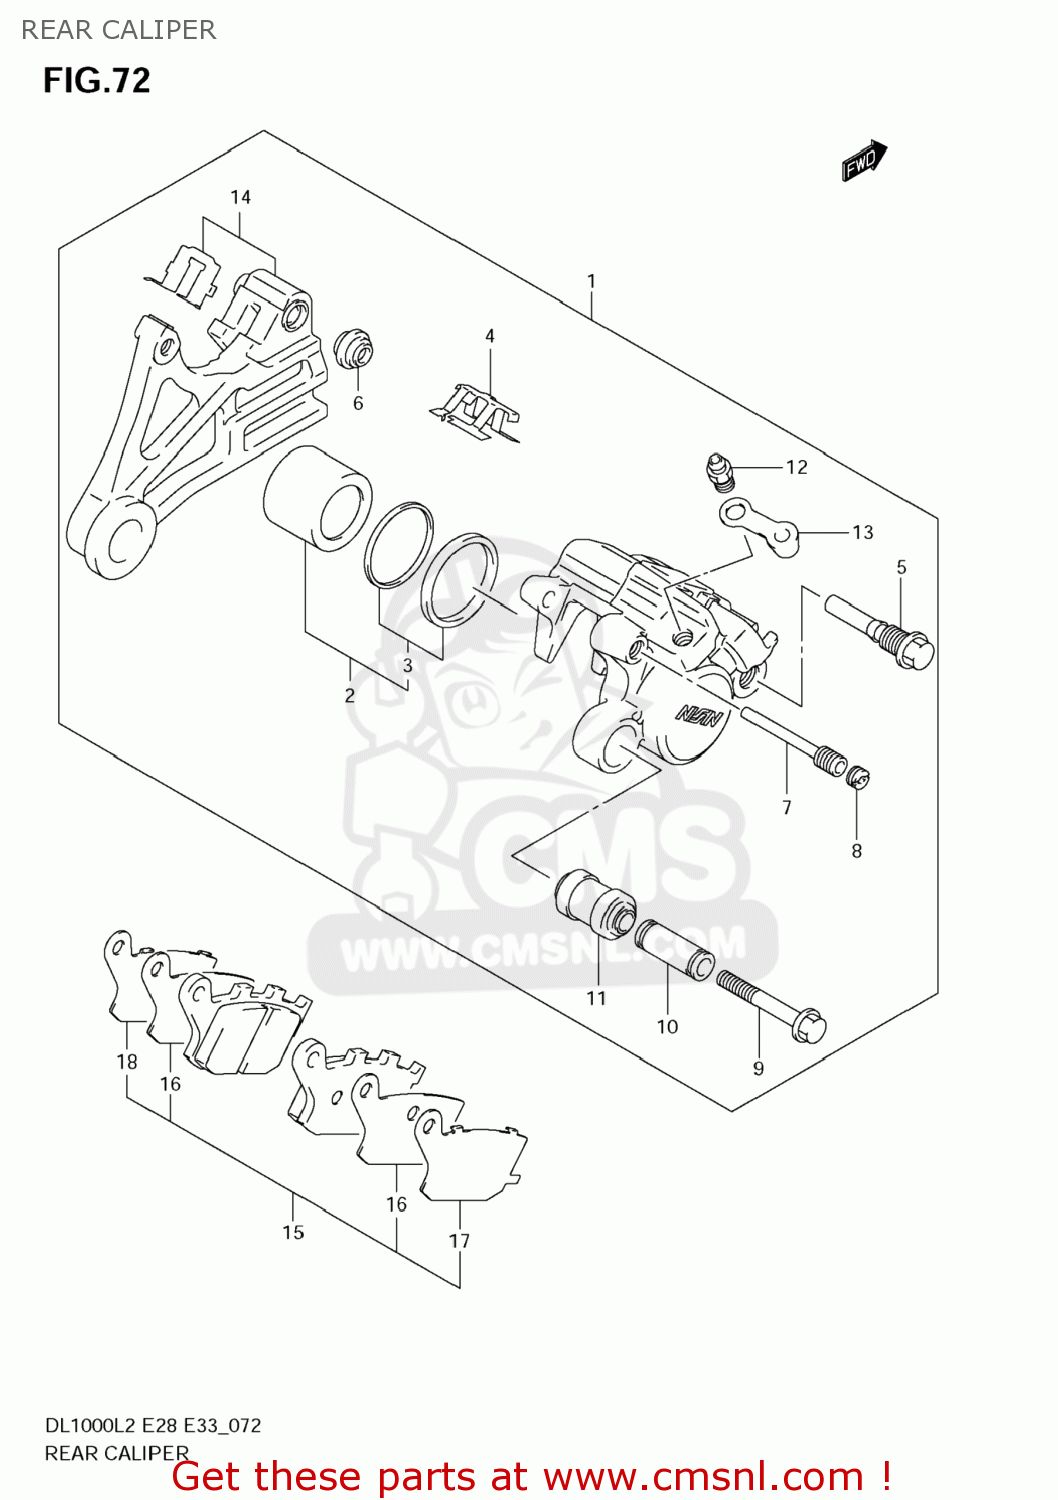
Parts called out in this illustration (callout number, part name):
1	CALIPER ASSY,RR
2	PISTON SET
3	SEAL SET,PISTON
4	SPRING,PAD
5	BOLT
6	BOOT
7	PIN,PAD
8	PLUG,PIN
9	BOLT
10	SLEEVE
11	BOOT,SLEEVE
12	BLEEDER
13	CAP,BLEEDER
14	BRACKET
15	PAD & RETAINER SET
16	INSULATOR
17	RETAINER
18	RETAINER
